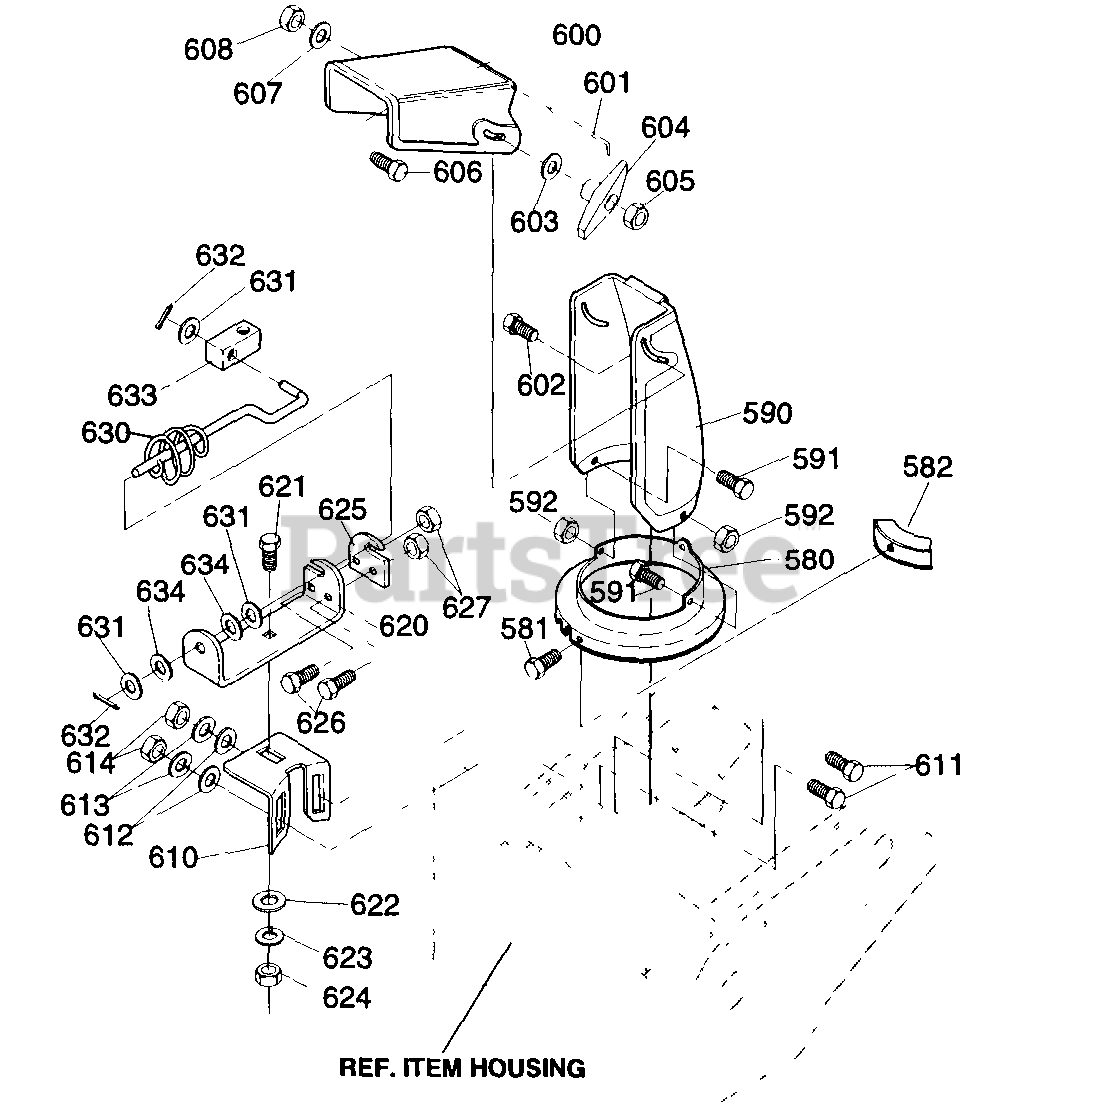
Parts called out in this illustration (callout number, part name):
580	RING, LOWER CHUTE
581	SCREW, 1/4-14X.63 HWATAP
582	CLIP, CHUTE RING PLASTIC
590	LOWER CHUTE
591	SCREW, 1/4-20X .50 HHC
592	NUT 1/4-20
600	CHUTE, UPR SRS W/O HDLE
601	HINGE WIRE
603	WASHER, FLAT .344X .69X.
604	KNOB, W/NUT
605	NUT, 5/16-18 REGHEX
606	SCREW, 5/16-18X.75
607	WASHER, FLAT .344X .69X.
608	NUT, 5/16-18 REGHEXCTRLK
610	MP BRACKET, WORM ADJ
612	WASHER, FLAT .344X .69X.
613	WASHER, HVSPTLK .328X.60X
614	NUT, 5/16-18 REGHEX
620	MP BRACKET, CHUTE ROD HOLDER
622	WASHER, FLAT .344X .69X.
623	WASHER, HVSPTLK .328X.60X
624	NUT, 5/16-18 REGHEX
625	PLATE, CHUTE ROD
626	SCREW, 1/4-20X .50 HHC
627	NUT, 1/4-20 REGHEXCTRLK
630	ROD, ASSY CHUTE LWR
631	WASHER, FLAT .40X.75X.025
632	PIN, COTTER .090/.086X.75
633	BLOCK, PIVOT PLASTIC
